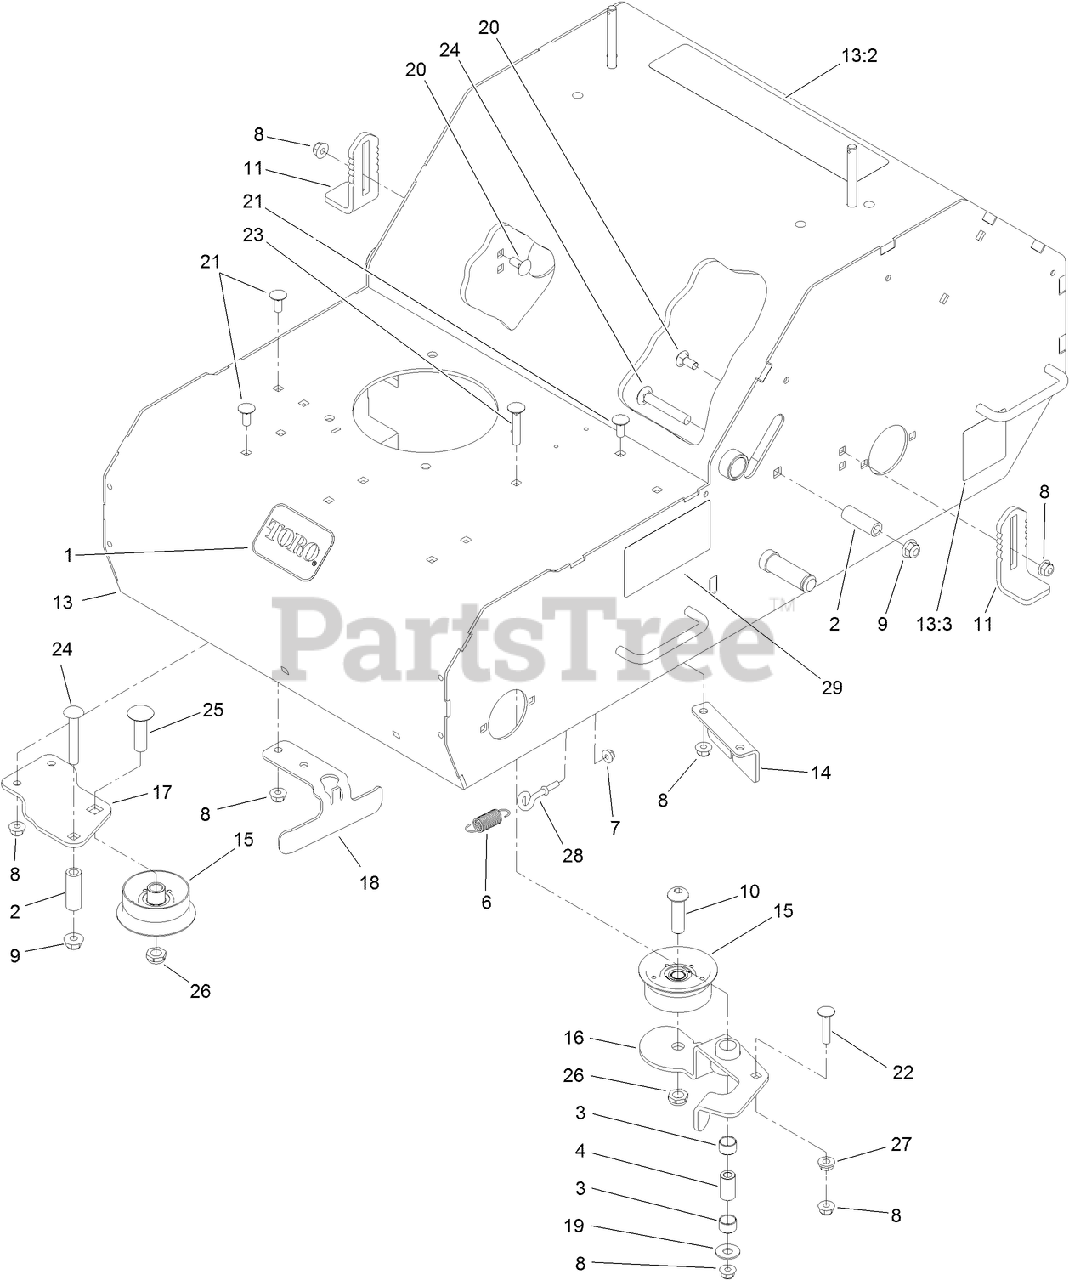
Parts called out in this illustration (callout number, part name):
1	DECAL
2	SPACER
3	BEARING
4	BUSHING-ARM, IDLER
6	SPRING
7	NUT-HF
8	NUT-HF, NI
9	NUT-HF, NI
10	SCREW-HSBH
11	STOP-DEPTH
13	FRAME ASM
13:2	DECAL-WARNING, AERATOR
13:3	DECAL-WARNING
14	BRACKET-MOUNT, CABLE
15	PULLEY-IDLER, FLAT
16	ARM-IDLER
17	BRACKET-MOUNT, PULLEY
18	GUIDE-BELT
19	WASHER-FLAT
20	BOLT-CARR
21	SCREW-CARR
22	BOLT-CARR
23	SCREW-CARR
24	SCREW-CARR
25	SCREW-CARR
26	NUT-LOCK, NI
27	NUT-HF
28	BOLT-EYE
29	DECAL-LIFT LOCK
